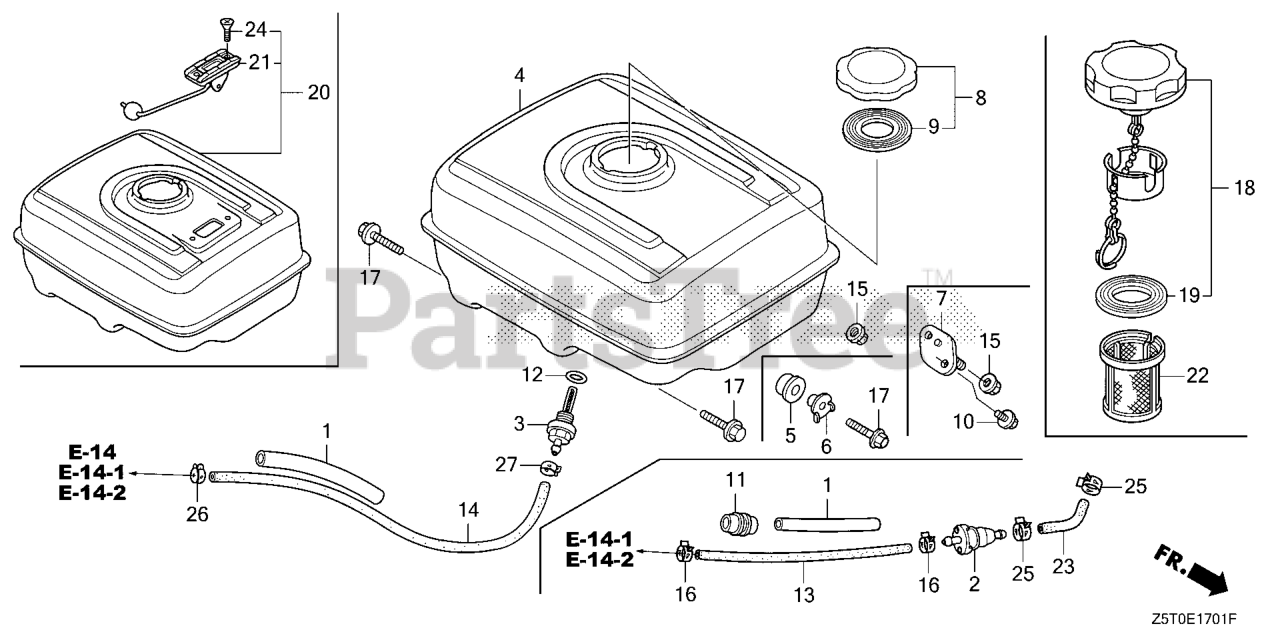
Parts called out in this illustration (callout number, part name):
1	RUBBER, SUPPORTER (107MM)
3	JOINT, FUEL TANK
4	TANK, FUEL *NH1* (BLACK)
4	TANK, FUEL *NH31* (MCKINLEY WHITE)
12	O-RING (14MM) (ARAI) Use up to Engine SN 2949254.
14	TUBE, FUEL (4.5X235) (FKM)
15	NUT, FLANGE (8MM)
17	BOLT, FLANGE (8X25)
18	CAP, FUEL FILLER
19	GASKET, FUEL FILLER CAP
22	FILTER, FUEL (FROM 1204807)
26	CLIP, TUBE (D8)
27	CLIP, TUBE (D8)
